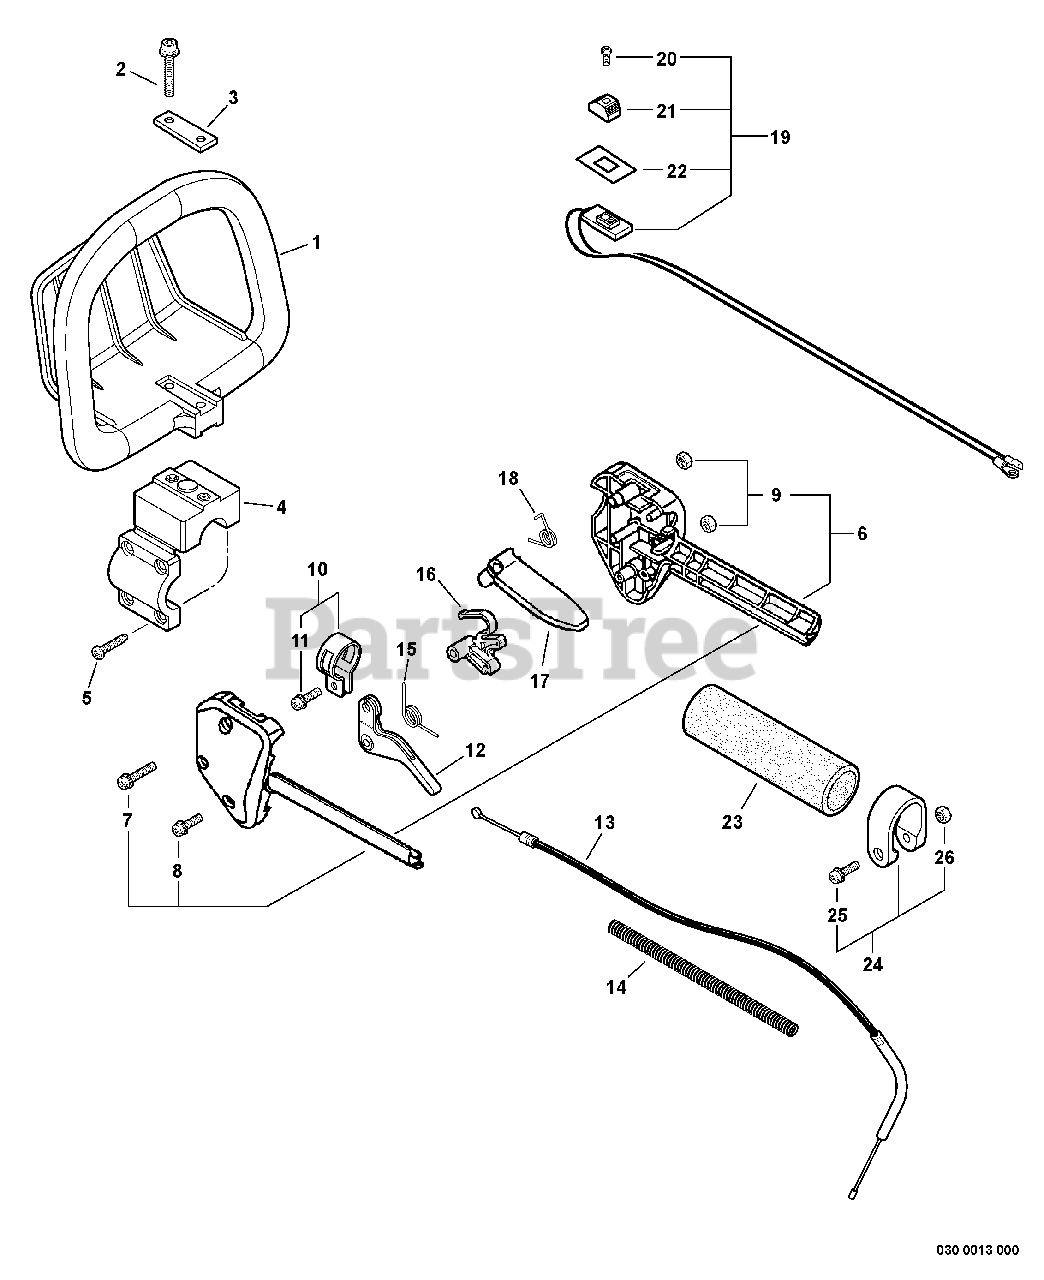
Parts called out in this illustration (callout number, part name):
1	HANDLE - FRONT
2	SCREW - 5X30
4	BRACKET, HANDLE
5	SCREW - 5
6	CONTROL HANDLE KIT
7	SCREW - 5X35
8	SCREW - 5X25
10	CLAMP KIT
11	SCREW - 5X14
12	TRIGGER, THROTTLE
13	CABLE, THROTTLE
14	TUBE, PROTECTIVE - CORRUGATED
15	SPRING, TRIGGER
16	LOCKOUT, THROTTLE
17	LEVER, TRIGGER LOCKOUT
18	SPRING, LOCKOUT LEVER
19	IGNITION SWITCH ASSY
20	SCREW - 3X10
21	KNOB, SWITCH - ORANGE
22	COVER, SWITCH - STOP
23	GRIP, HANDLE
24	CLAMP KIT
25	SCREW - 5X28
